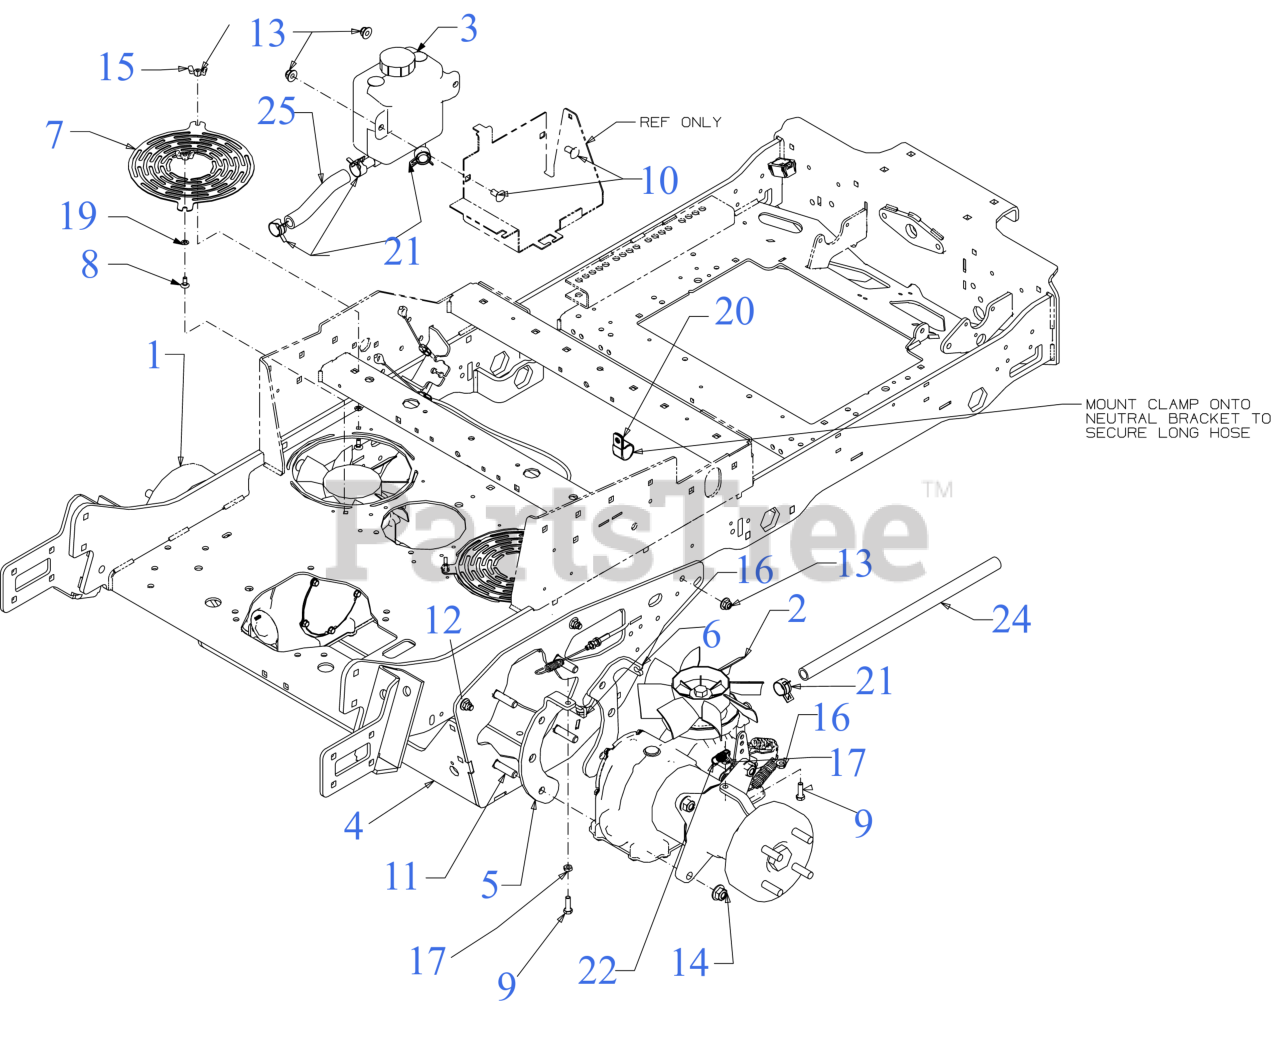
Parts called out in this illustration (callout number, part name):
1	TRANSMISSION/MOTOR ASSEMBLY (LH) (PARKER)
2	TRANSMISSION/MOTOR ASSEMBLY (RH) (PARKER)
3	HYDRO TANK ASSEMBLY
4	TRANSMISSION MOUNTING BRACKET
7	TRANSMISSION COVER PLATE
8	CARRIAGE BOLT 1/4-20 x .62
9	SCREW 5/16-18 x 1.0 GR5
10	CARRIAGE BOLT 3/8-16 x .750 GR5
11	CARRIAGE BOLT 1/2-13 GR5
12	CARRIAGE BOLT 3/8-16 X1.25 GR5
15	WING NUT 1/4-20
16	HEX FLANGE NUT
19	RETAINER-BOLT .25ID x .50OD
20	HOSE CLAMP 1.0"
21	HOSE CLAMP
22	EXTENSION SPRING .500 OD x 1.71
24	OIL HOSE 5/8 ID x 18.00 LG
